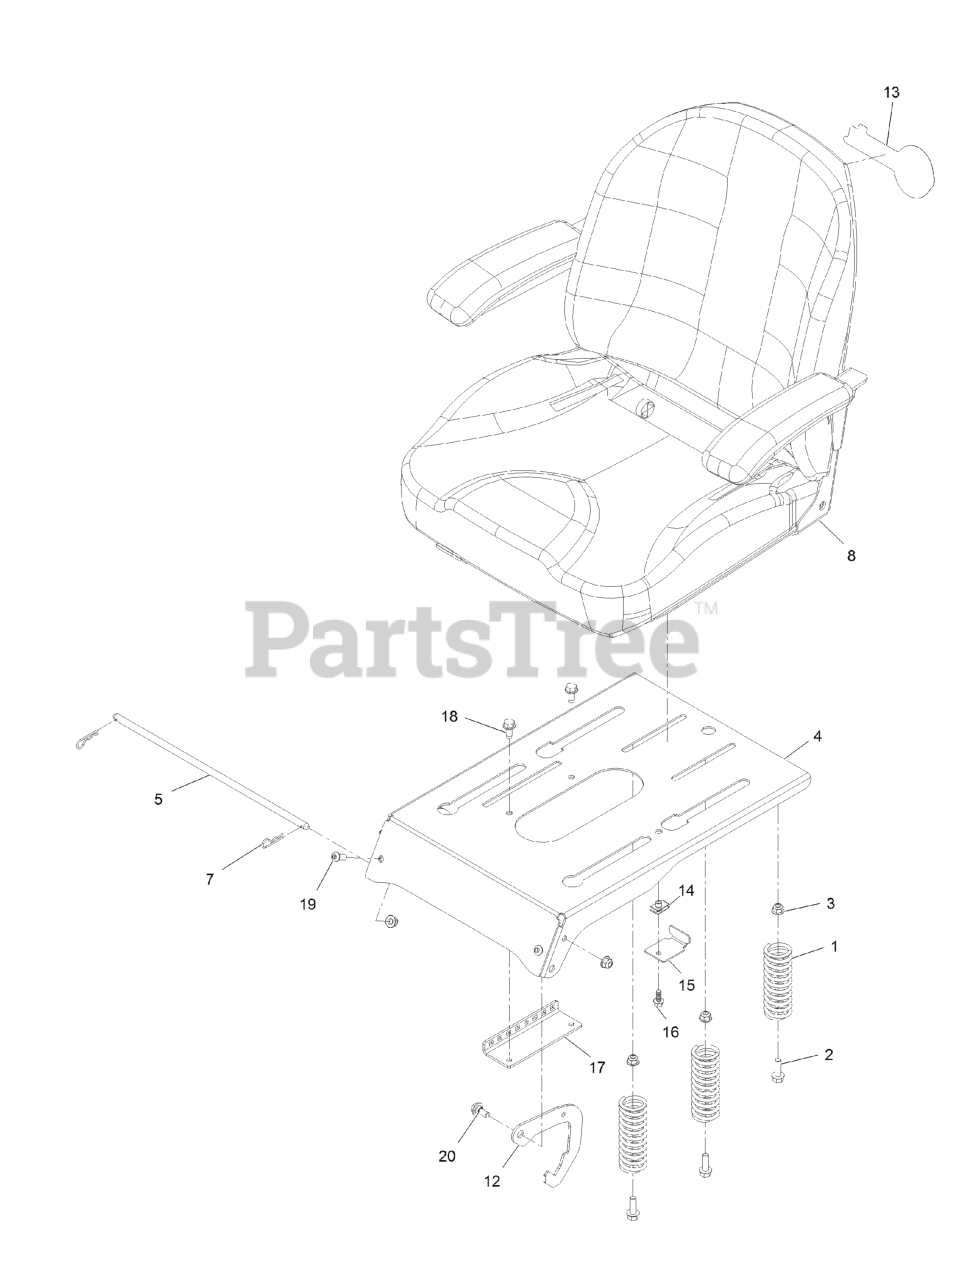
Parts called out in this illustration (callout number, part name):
1	SPRING-COMPRESSION
2	SCREW-HHF
3	NUT-HF, NI
4	PAN-SEAT, DELUXE
5	ROD-PIVOT, NARROW
7	PIN-COTTER
8	SEAT ASM, EXMARK
12	Seat Latch
13	DECAL-EXMARK LOGO
15	Bracket-Stop, Seat
16	SCREW-HHF
17	BRACKET-LATCH, SEAT
18	Screw-HWH 5/16-18 X 3/4 Tf
19	SCREW-HSBH
20	SCREW-SHOULDER
